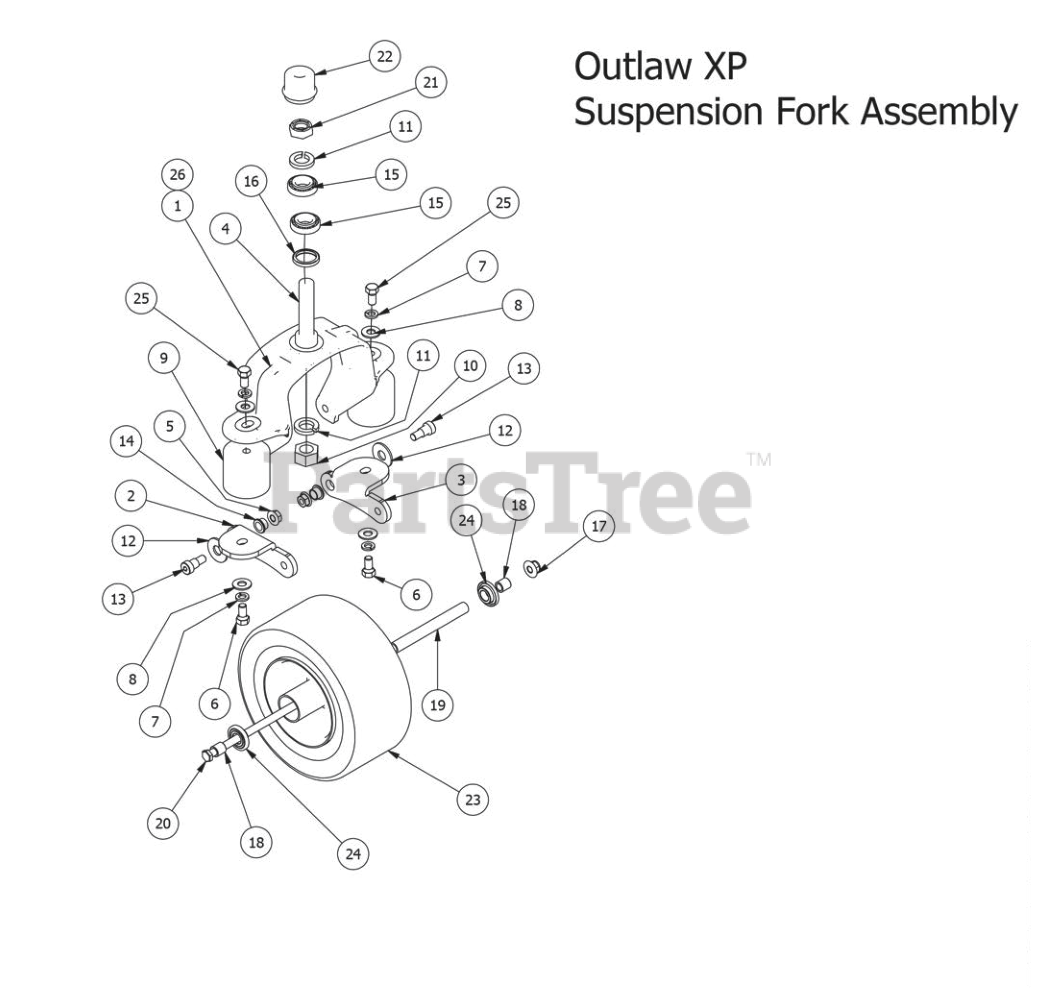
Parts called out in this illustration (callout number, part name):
1	Suspension Fork Top/Side Combo
2	Suspension Fork - Bottom Left
3	Suspension Fork - Bottom Right
4	Front Suspension Fork Spindle
5	1/2" Flange Nut
6	1/2" x 1" Hex Bolt
7	1/2" Lock Washer
8	1/2" Washer (Grade 8)
9	Vibration Mount-Red Dot
10	1" Fine Thread Nut
11	1" Lock Washer
12	5/8" Flat Washer
13	5/8" x 5/8" Shoulder Bolt
14	Bronze Bushing- SF-2024-8
17	1/2-13 Nylon Flange Nut-Orange
18	3/4 OD x 1/2 ID x 3\4 Length
19	Front Wheel Spanner
20	1/2" x 10" Bolt
21	1" Fine Thread 1/2 Nut
22	Dust Cover
23	Tire and wheel assembly
24	1-3/4" Bearing-Large Bore Front Rim
25	1/2-13 x 1-1/4 Hex Bolt
26	Suspension Fork Assembly
